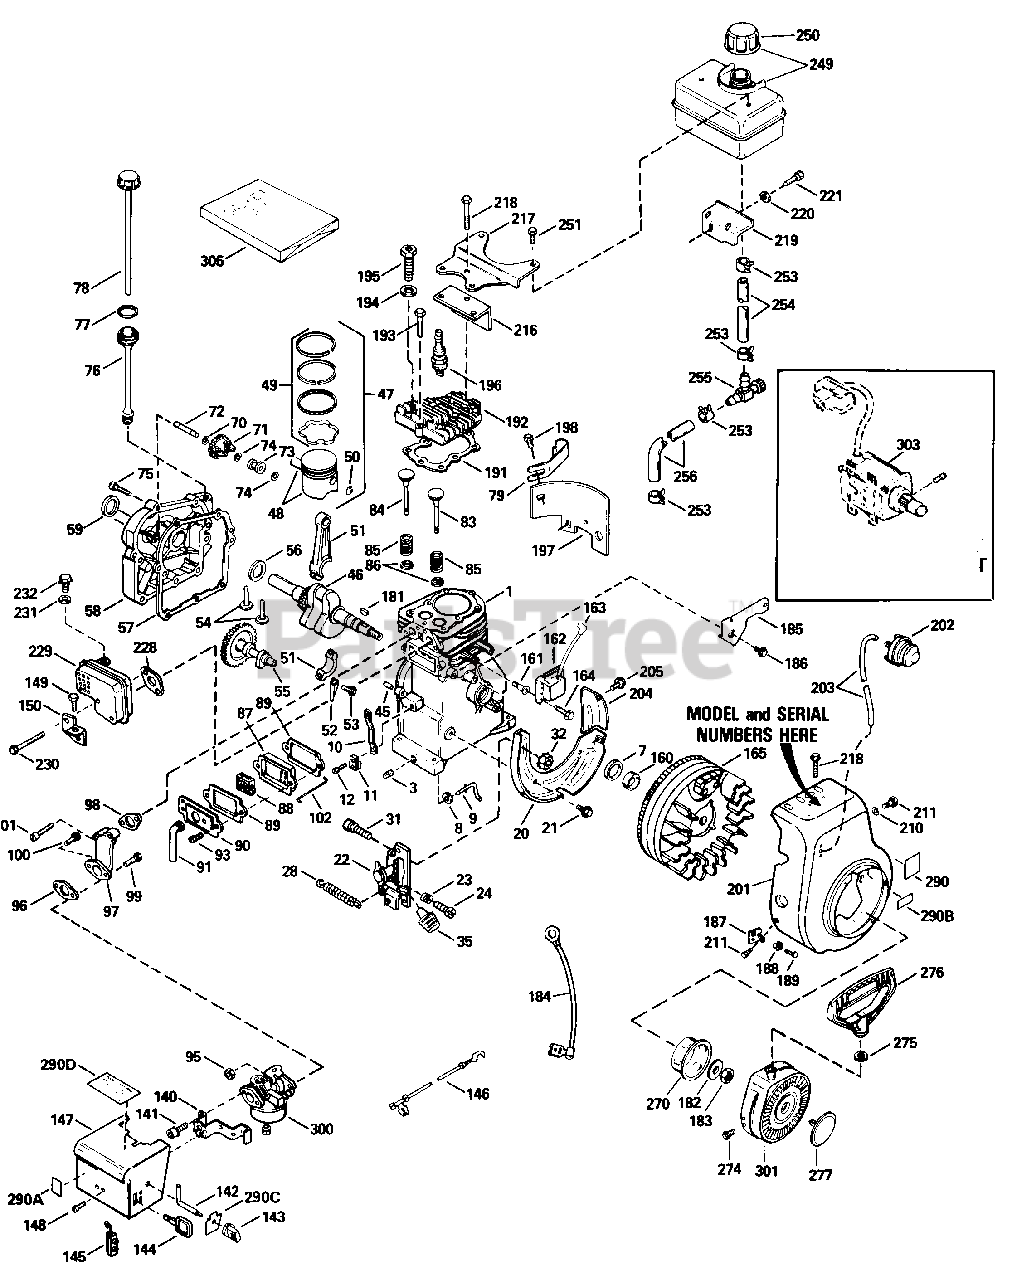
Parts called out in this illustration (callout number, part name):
1	Cylinder Ass'y.
3	Plug, Pipe, 1/4-18
7	Seal, Oil
8	Washer, Flat
9	Rod, Governor
10	Lever, Governor
11	Clamp, Governor Lever
12	Screw, Hex Washer Hd., 8-32 x 5/1 6
20	Baffle, Blower Housing
21	Screw, Hex Washer Hd. Durlok, 1/4-20 x 5/8
22	Control Ass'y., Bracket
23	Spring, Compression
24	Screw, Fil. Hd., 5-40 x 7/16
28	Spring, Extension
31	Screw, Fil. Hd. Sems, 8-32 x 1/2
32	Nut, Lock, 8-32
35	Knob, Speed Control
45	Pin, Dowel
46	Crankshaft Ass'y.
47	Piston, Pin & Ring Ass'y. (Std.)
48	Piston & Pin Ass'y. (Std.)
49	Ring Set, Piston (Std.)
50	Ring, Piston Pin Retaining
51	Rod Ass'y., Connecting
52	Dipper, Oil
53	Screw, Connecting Rod
54	Lifter, Valve
55	Camshaft
56	Washer, Thrust
57	Gasket, Cylinder Cover
58	Cover, Cylinder
59	Seal, Oil
70	Washer, Flat
71	Gear, Governor
72	Shaft, Mechanical Governor
73	Spool, Governor
74	Ring, Retaining
75	Screw, Hex Hd. Sems, 1/4-20 x 1-1/4
76	Tube Ass'y., Oil Fill
79	Clip, Oil Fill
83	Valve, Exhaust (Std.)
84	Valve, Intake (Std.)
85	Spring, Valve
86	Cap, Valve Spring
87	Body, Valve Cover
88	Element, Valve Body
89	Gasket, Valve Cover
90	Cover, Breather
91	Tube, Breather
93	Screw, Fil. Hd. Sems, 10-24 x 1/2
95	Nut & Lock Washer Ass'y., 1/4-28
96	Gasket, Carburetor
97	Pipe, Intake
98	Gasket, Intake
99	Screw, Hex Hd., 1/4-28 x 7/8
100	Screw, Hex Hd., 1/4-28 x 1-11/16
101	Screw, Fil. Hd. Sems, 1/4-20 x 1 -19/32
102	Link, Governor to Throttle
140	Bracket, Choke
141	Screw, Fil. Hd. Sems, 10-32 x 1/2
142	Rod, Choke
143	Knob, Choke Control
144	Key, Ignition
145	Terminal Ass'y.
146	Wire, Ground
147	Cover, Carburetor
148	Screw, Pan Hd. Sems, 8-32 x 5/16
149	Screw, Hex Hd. Sems, Taptite, 10-24 x 3/8
150	Bracket, Carburetor Cover
160	Spacer, Flywheel Key
161	Stud, Solid State Mounting
162	Solid State Ass'y.
163	Cover, Spark Plug
164	Screw, Hex Hd. Sems, 10-24 x 1
165	Flywheel
181	Key, Flywheel
182	Washer, Belleville
183	Nut, Flywheel
184	Wire, Ground
185	Bracket, Hold Down
186	Screw, Hex Washer Hd. Self-Tap Sems, 1/4-15 x 7/8
187	Bracket, Grommet Mounting
188	Grommet, Plastic
189	Screw, Pan Hd. Taptite, 8-32 x 318
191	Gasket, Cylinder Head
192	Head, Cylinder
193	Screw, Hex Flange Hd., 5/16-18 x 1-1/2
194	Washer, Flat
195	Screw, Special Hex Hd., 5/16-18 x 1-1/2
196	Plug, Spark
197	Extension, Blower Housing
198	Screw, Fil. Hd. Sems, 10-24 x 1/2
201	Housing, Blower
202	Primer Ass'y.
203	Line, Primer
204	Extension, Baffle
205	Screw, Hex Washer
210	Washer, Flat
211	Screw, Hex Hd. Sems, 1/4-28 x 7/16
216	Baffle, Heat
217	Plate, Fuel Tank
218	Screw, Hex Flange Hd., 5/16-18 x 2
219	Bracket, Fuel Tank Mounting
220	Washer, Flat
221	Screw, Hex Hd., w/Belleville Washer, 1/4-20 x 11/16
228	Gasket, Exhaust
229	Muffler
230	Screw, Fil. Hd. Sems, 1/4-20 x 2-1/2
231	Washer, Flat
232	Screw, Hex Washer Hd. Sems, 1/4-20 x 1/2
249	Tank Ass'y., Fuel
250	Cap, Fuel Tank
251	Screw, Hex Washer Hd. Self-Tap Sems, 1/4-15 x 7/8
253	Clamp, Fuel Line
254	Line, Fuel
255	Valve, Shut-Off
256	Line, Fuel
270	Cup, Starter
274	Washer, Flat
275	Washer, Flat
276	Handle, Starter
277	Plug, Starter
290	Decal, Name
290A	Decal, Instruction
290B	Decal, Primer
290C	Decal, Choke
290D	Decal, Warning
300	Carburetor
301	Starter, Rewind
303	Electric Starter Kit
305	Gasket Set
